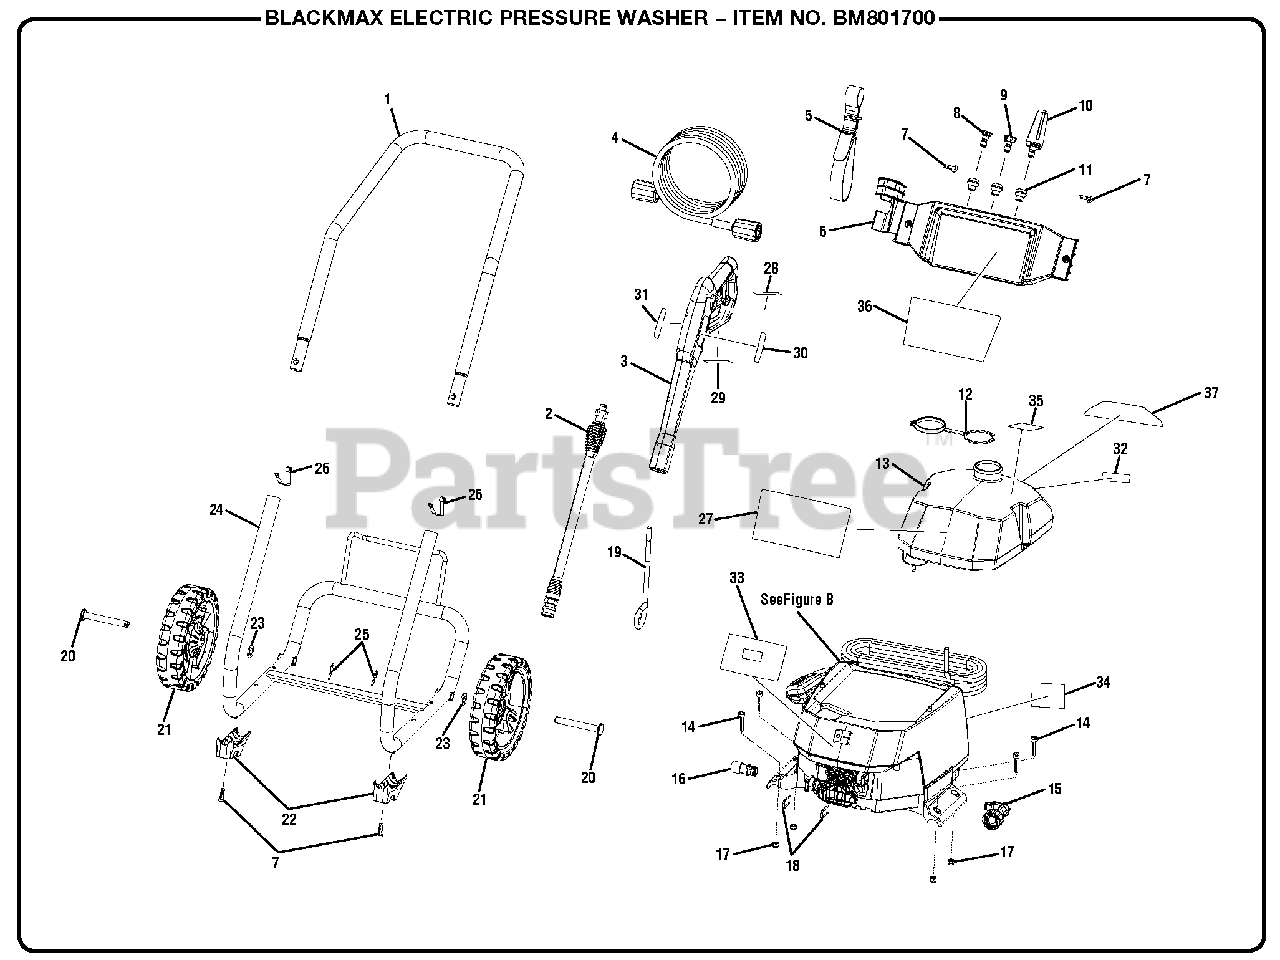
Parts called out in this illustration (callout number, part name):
1	Handle Assembly
2	Spray Wand
3	Trigger Handle
5	Hose Storage Strap
6	Performance Panel
7	Bolt (M6 x 20 mm, Philips Pan Hd.)
8	Soap Nozzle
9	15deg Nozzle
10	Turbo Nozzle
11	Nozzle Grommet
12	Soap Tank Cap
13	Soap Tank
14	Screw (M6 x 40 mm, Hex Hd.)
15	Inlet Pump Assembly
16	Outlet Pump Assembly
17	Lock Nut (M6)
19	Siphon Tube
20	Wheel Axle
23	Washer (OD125 x ID24 x 2t)
24	Frame Tubing
25	Hitch Pin
26	Spring Clip w/Button
27	Performance Label
28	Trigger Handle Rating Label
29	Trigger Handle Warning Label (French/Spanish)
30	Trigger Handle Label
31	Trigger Handle Warning Label (English)
32	Inquires Label
33	On/Off Switch Label
34	Danger Icon Label
35	Detergent Tank Label
36	Logo Label
37	Quick Start Label
